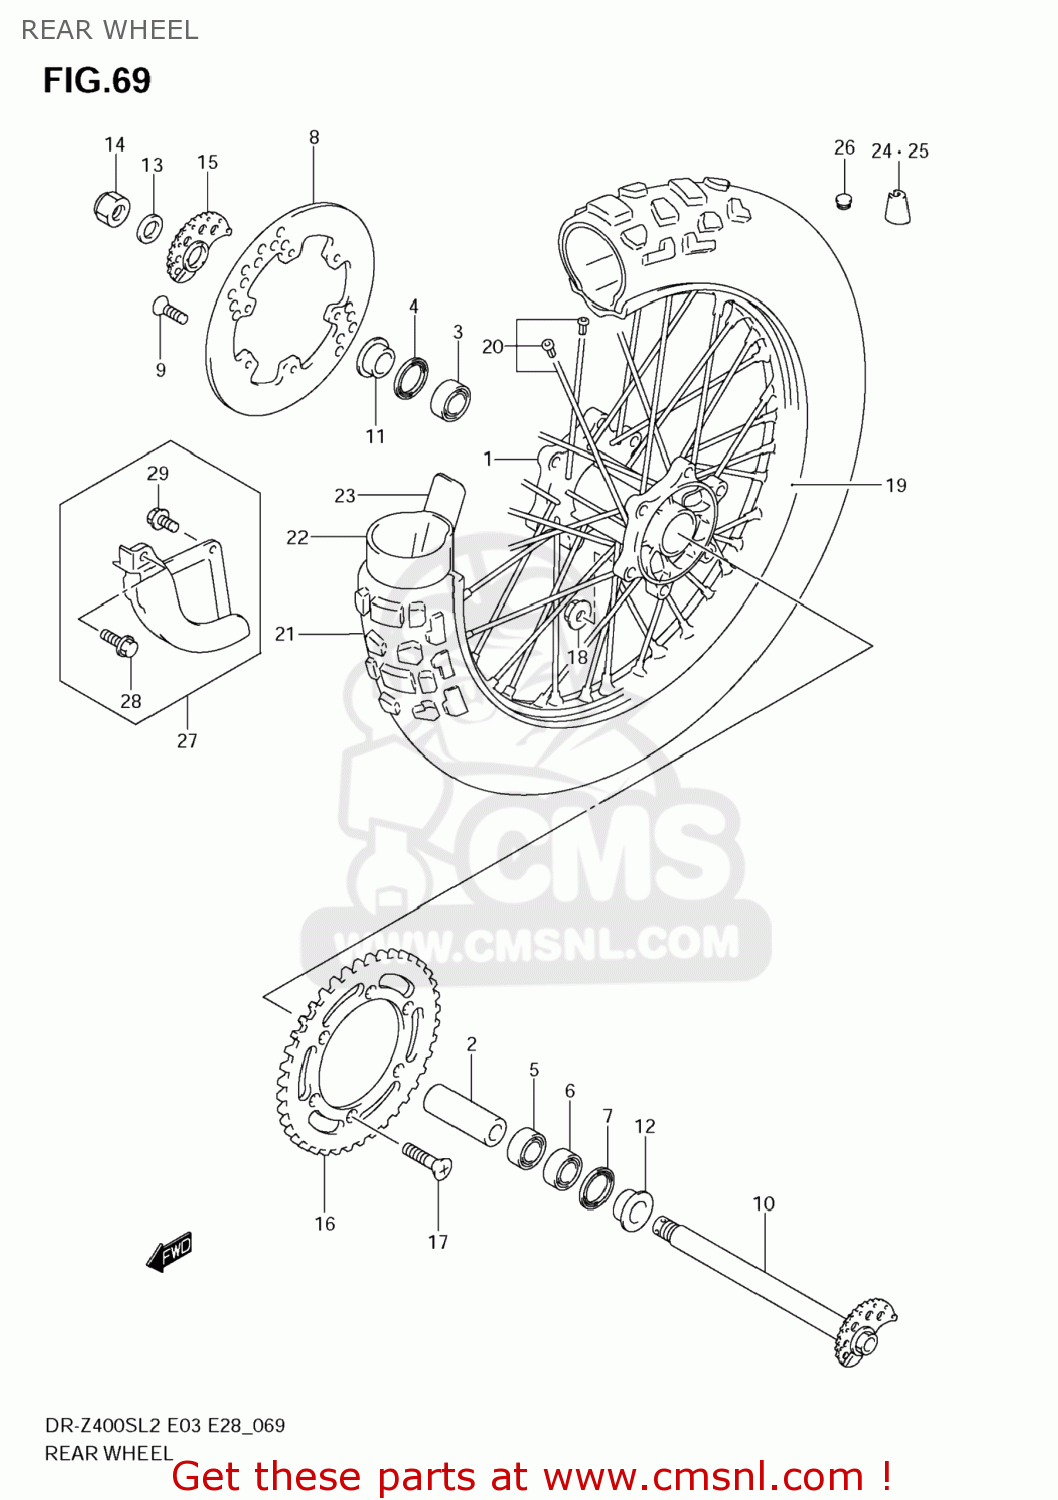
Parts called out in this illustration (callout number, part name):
1	HUB,RR WHEEL
2	SPACER,RR HUB BEARING
3	BEARING
4	SEAL(29X42X6)
5	BEARING
6	BEARING
7	SEAL,OIL(29X47X6)
8	DISC,RR BRAKE
9	SCREW
10	AXLE,RR
11	SPACER,RR AXLE
12	SPACER,RR AXLE
13	WASHER(19X32X3.2)
14	NUT
15	ADJUSTER,CHAIN,R
16	SPROCKET,RR(44T,S45C)
17	BOLT(8X30.5)
18	NUT
19	RIM,RR WHEEL(18X2.15 AL)
20	SPOKE SET,RR WHEEL
21	TIRE,RR(120/90-18 65P)
22	TUBE ASSY,WHEEL INNER
23	PROTECTOR,WHL INR TUBE
24	BALANCER,WHEEL(20G)
25	BALANCER,WHEEL(30G)
26	CAP(OD:12)
27	COVER SET,RR BRAKE DISC
28	BOLT
29	BOLT
